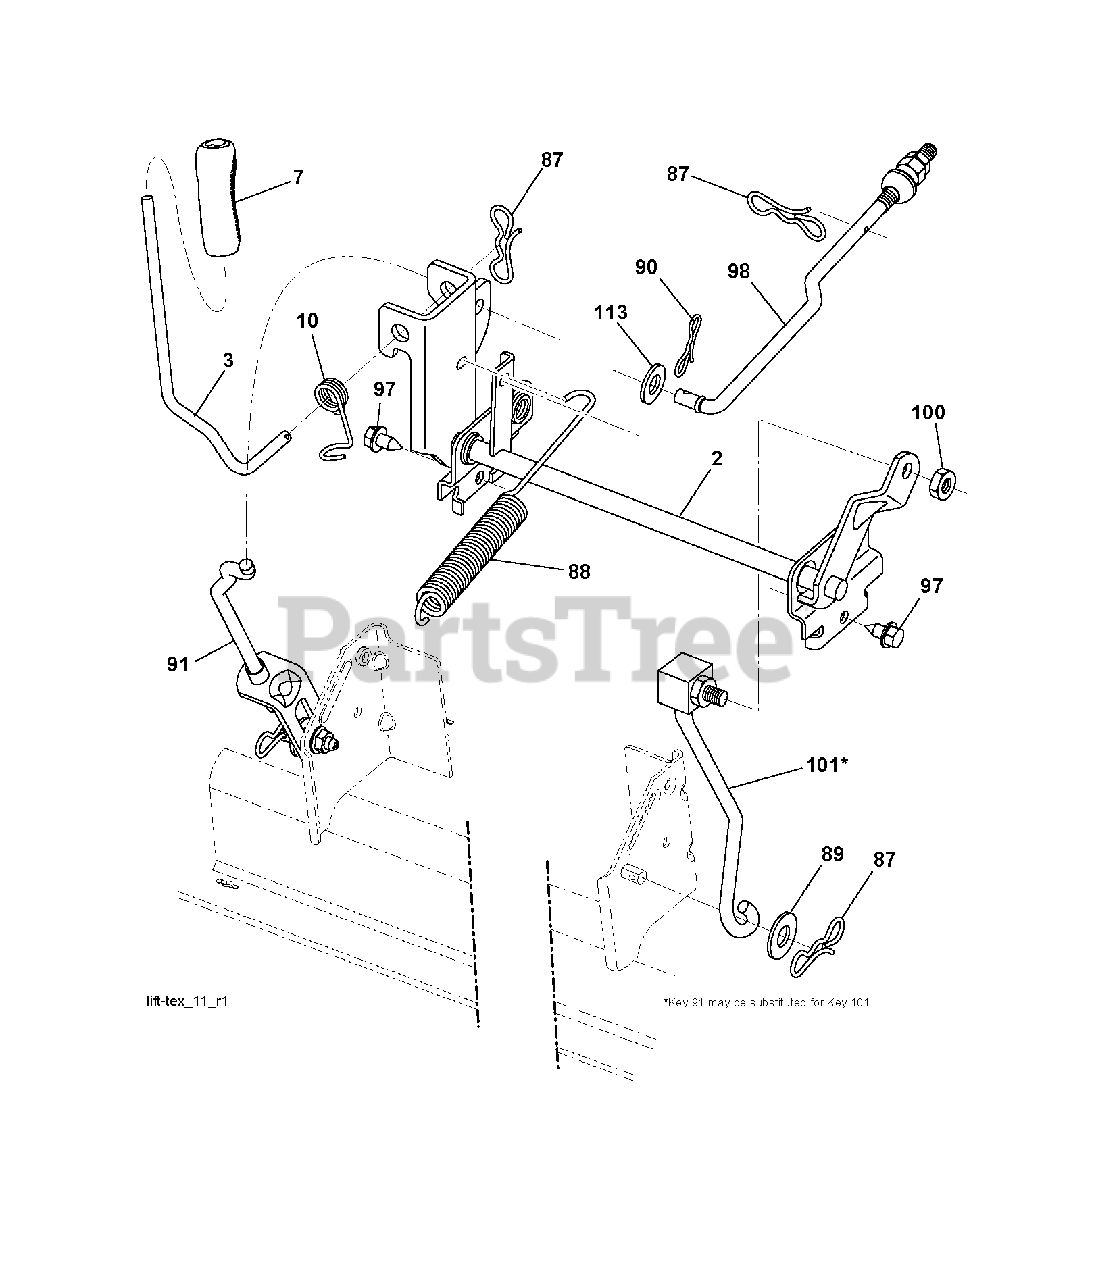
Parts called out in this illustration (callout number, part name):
2	SHAFT.ASM.CROSS.LIFT
3	LEVER.LIFT.HANDLE.LT
7	GRIP.HANDLE.LIFT.PVC.BLACK
10	SPRING.TORSION.LIFT.HANDLE
87	PIN.COTTER.7/16.BOW TI.
88	SPRING.LIFT.ASSIST
89	WASHER.CLEAR.ZINC
90	PIN.COTTER.5/16.BOW TI
91	LINK.ASM.LIFT.REAR
97	SCREW, 3/8-16X3/4
98	LINK.ASM.SUSP.FRONT.MWR.10.5
100	LOCKNUT
101	LINK.ASM.LIFT.FIXE.38/42/46"
